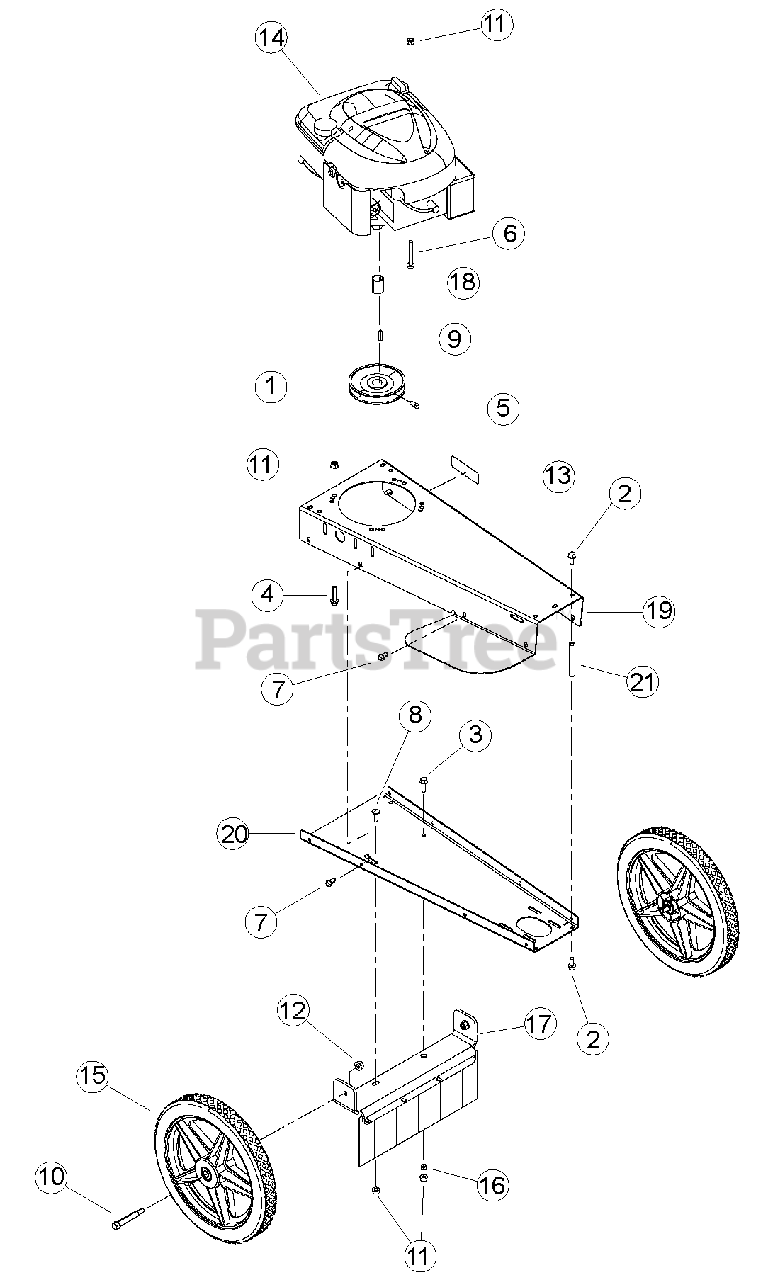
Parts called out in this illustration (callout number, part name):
1	PULLEY, 5.0 X 7/8 AB
2	BOLT, 5/16 X 3/4 FLANGE NC
3	BOLT, 5/16 X 1 FLANGE NC
4	BOLT, 5/16 X 1-1/2 FLANGE NC
5	SCREW, 5/16-18 X 5/8 SQ HD SET
6	BOLT, 5/16-18 X 2-1/2 FLANGE NC
7	SCREW, 11/32 X 7/8 HWH AB THREAD ZP
8	BOLT, 5/16 X 1" GR5 CRG ZP
9	SQUARE KEY, 3/16 X 1.00" LG
10	BOLT, 3/8-16 X 3-1/4 FLANGED SHOULDER
11	NUT, 5/16-18 NYLOCK-FLANGE
12	NUT, 3/8-16 NYLOCK FLANGE
13	DECAL, SERIAL NUMBER
14	ENGINE, 6.5 HP QUANTUM HD 50 STATE (FOR SERVICE SEE ENGINE OWNER'S MANUAL OR YOUR NEAREST AUTHORIZED BRIGGS & STRATTON INDUSTRIAL ENGINE DEALER.)
15	WHEEL, 14 X 1.75 TRIMMER
16	SPACER, .334 X .50 X .29
17	PLATE, TRIMMER AXLE
18	SPACER, 1-1/16 OD X 14 GA X 1.40
19	BODY, TRIMMER STANDOFF
20	BOTTOM, TRIMMER STANDOFF
21	STANDOFF, WHEELED TRIMMER BODY
